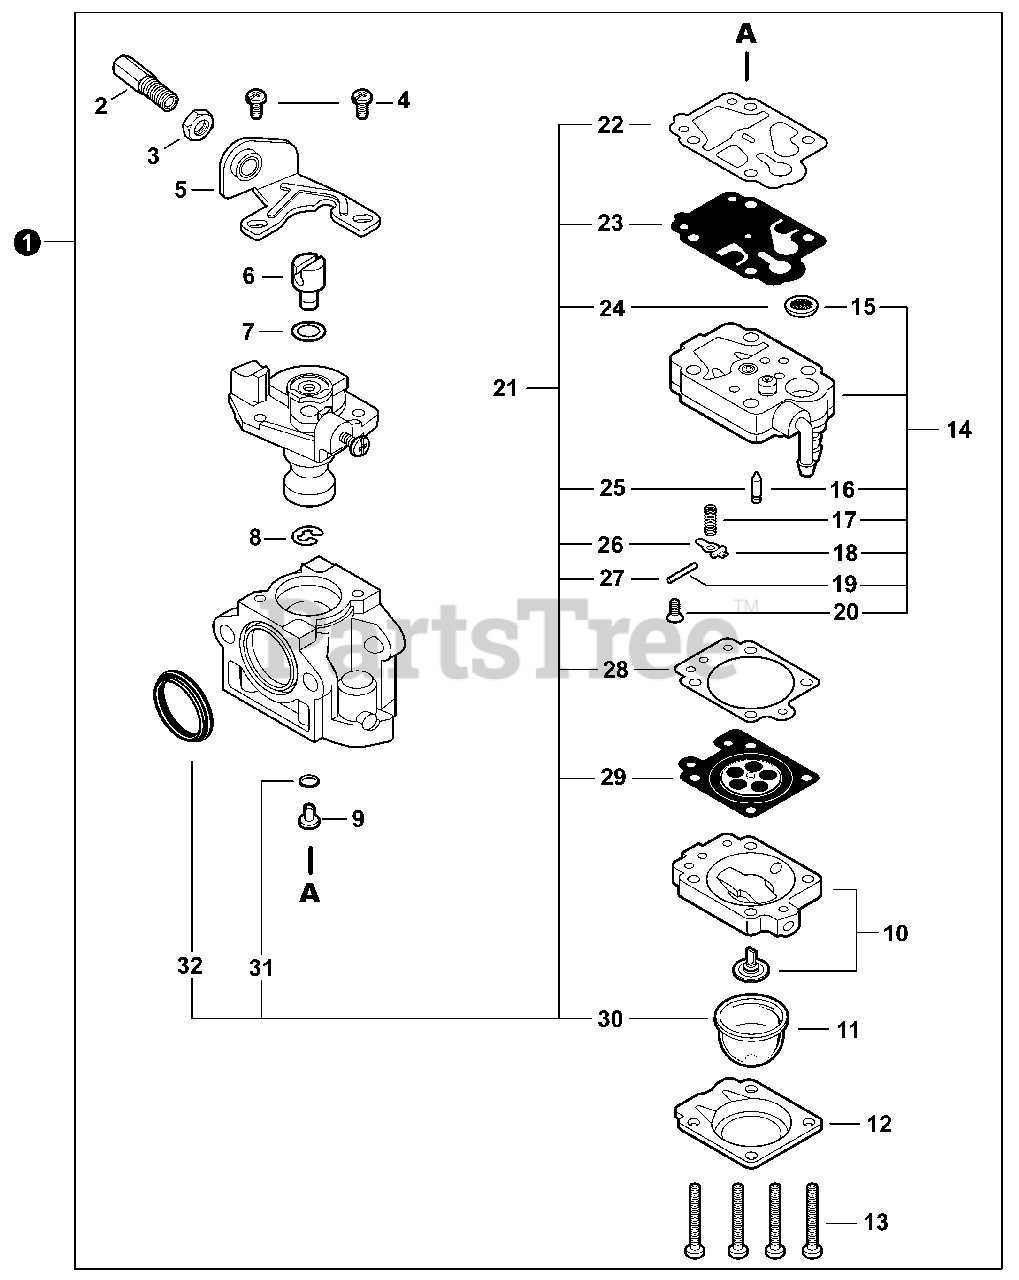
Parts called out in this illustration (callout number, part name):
1	CARBURETOR WYK-322
2	ADJUSTER, THROTTLE CABLE
3	NUT, ADJUSTER LOCK M7
5	BRACKET, THROTTLE CABLE
9	JET, MAIN
10	BODY ASSY, PURGE
11	BULB, PURGE
12	RETAINER, PURGE BULB
14	BODY ASSY, PUMP
15	SCREEN, FUEL INLET
16	VALVE, INLET NEEDLE
17	SPRING, METERING LEVER
18	LEVER, METERING
19	PIN, METERING LEVER
20	SCREW
21	REPAIR KIT, CARBURETOR
22	GASKET, PUMP
23	DIAPHRAGM, PUMP
24	SCREEN, FUEL INLET
25	VALVE, INLET NEEDLE
26	LEVER, METERING
27	PIN, METERING LEVER
28	GASKET, METERING DIAPHRAGM
29	DIAPHRAGM, METERING
30	BULB, PURGE
31	O-RING
32	RING, PACKING
